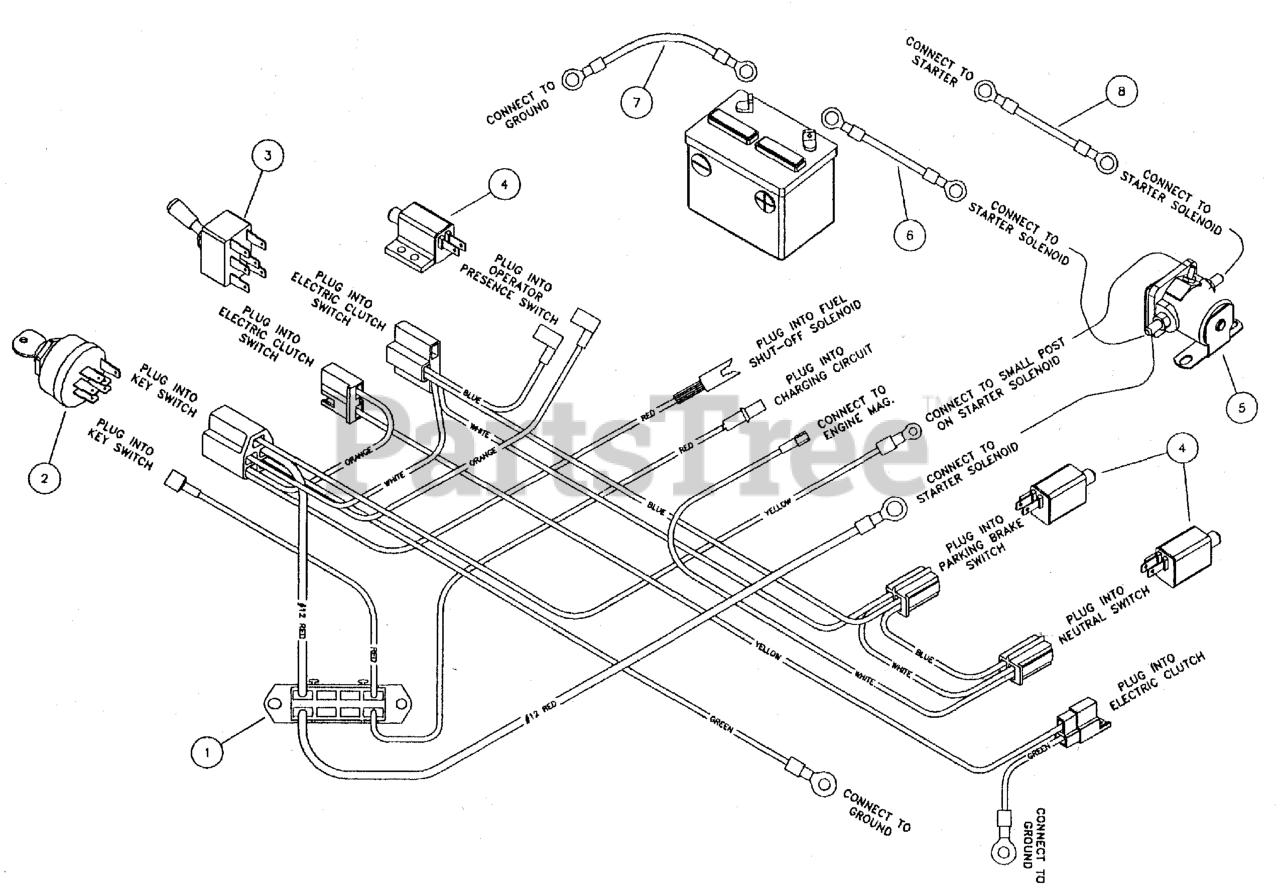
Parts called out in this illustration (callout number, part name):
1	DDSBVE Wire Harness
2	SWITCH, Ignition, Complete
3	SWITCH, Electric Clutch
4	SWITCH, PLUNGER, N.C.
5	SOLENOID, Starter
6	POSITIVE (+) BATTERY CABLE, 30"
7	BATTERY CABLE, NEG, 22, 1/4-5/16
8	POSITIVE (+) BATTERY CABLE, 22"
